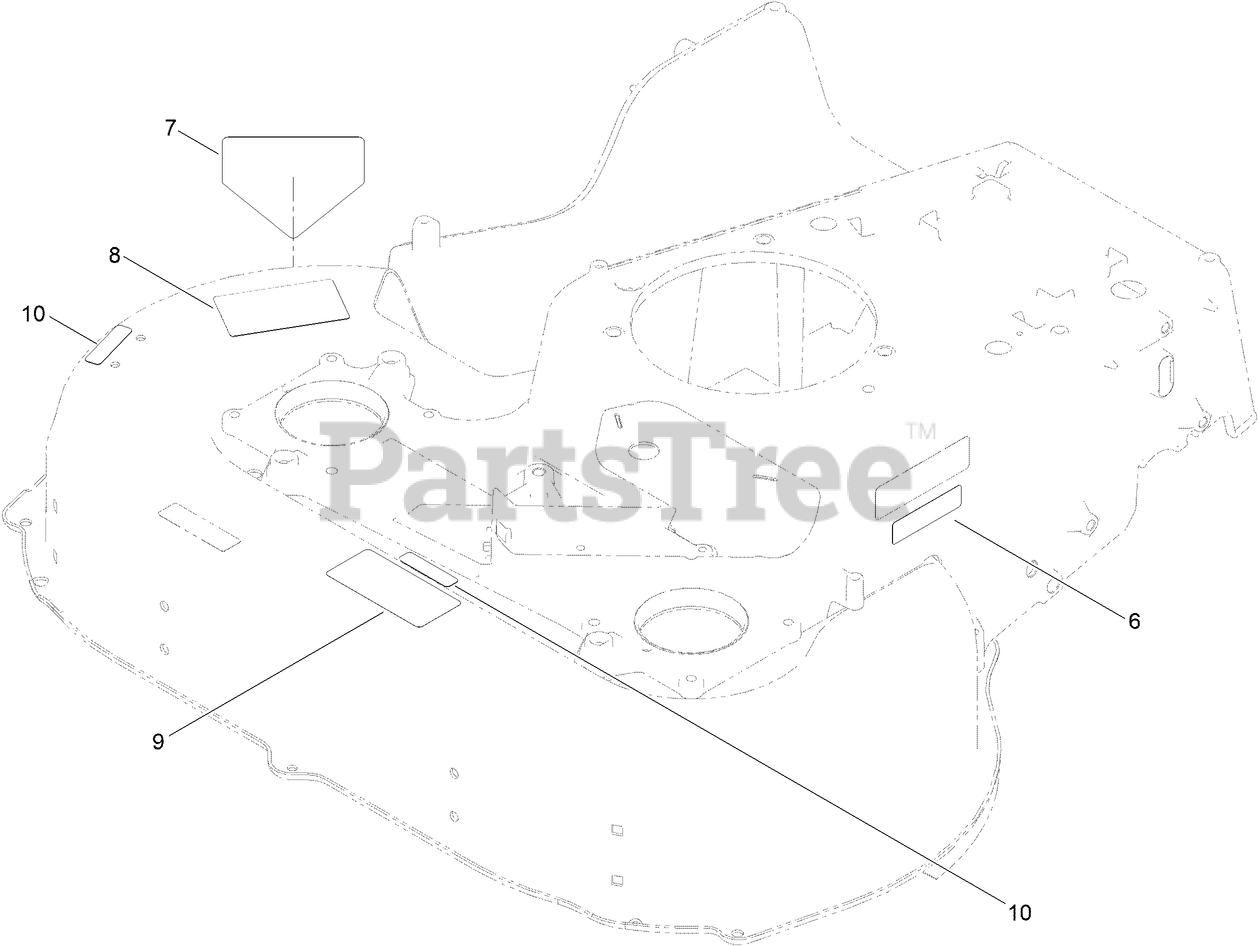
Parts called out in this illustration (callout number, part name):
6	DECAL-ARRESTOR, SPARK
7	DECAL-DANGER
8	DECAL-DANGER, CE
10	DECAL-WARNING
